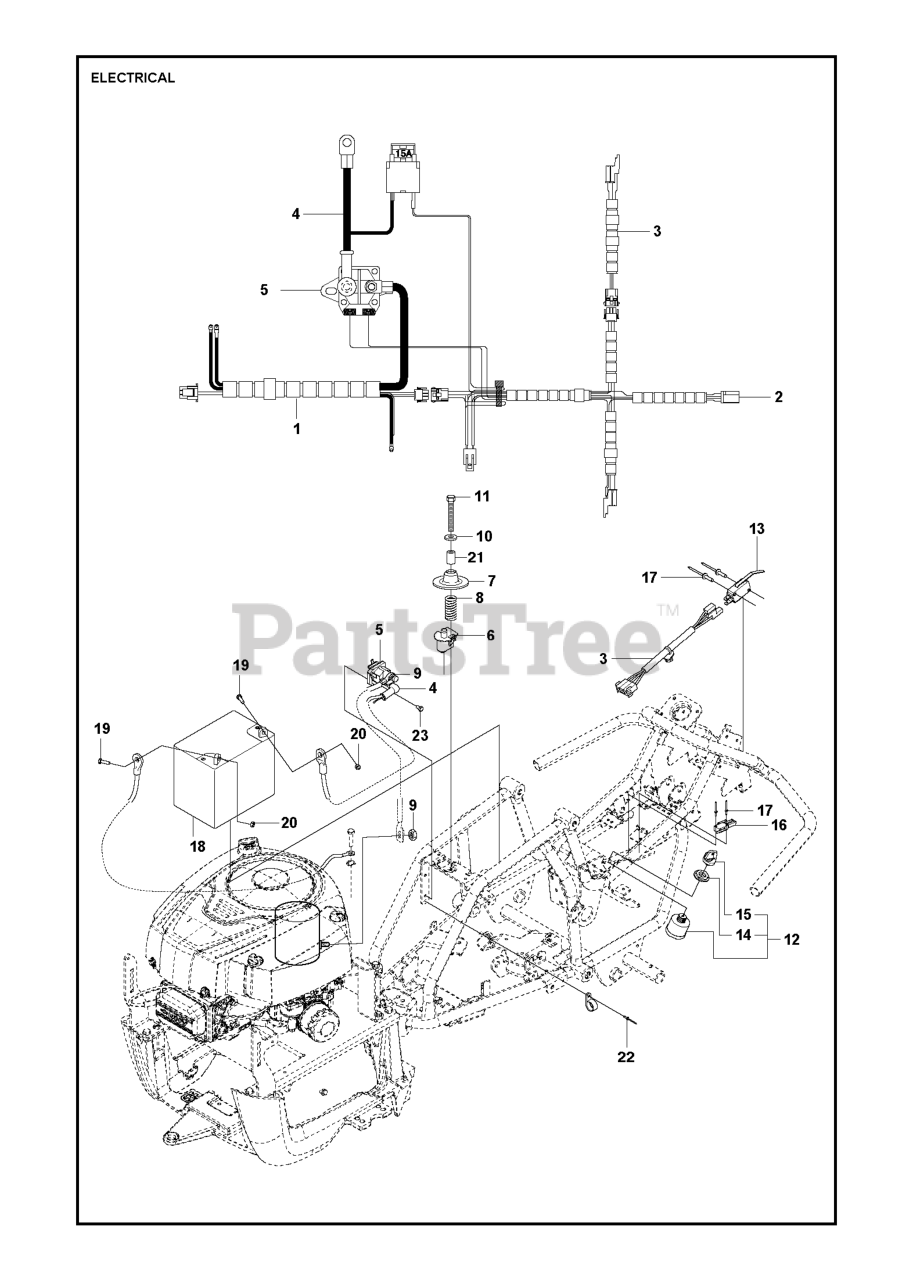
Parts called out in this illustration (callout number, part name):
10	WASHER BRB 8.4X17
11	SCREW
12	IGNITION SWITCH
15	IGNITION KEY
16	MICRO SWITCH
19	SCREW EHHM
21	SPACER TUBE
22	Rivet
